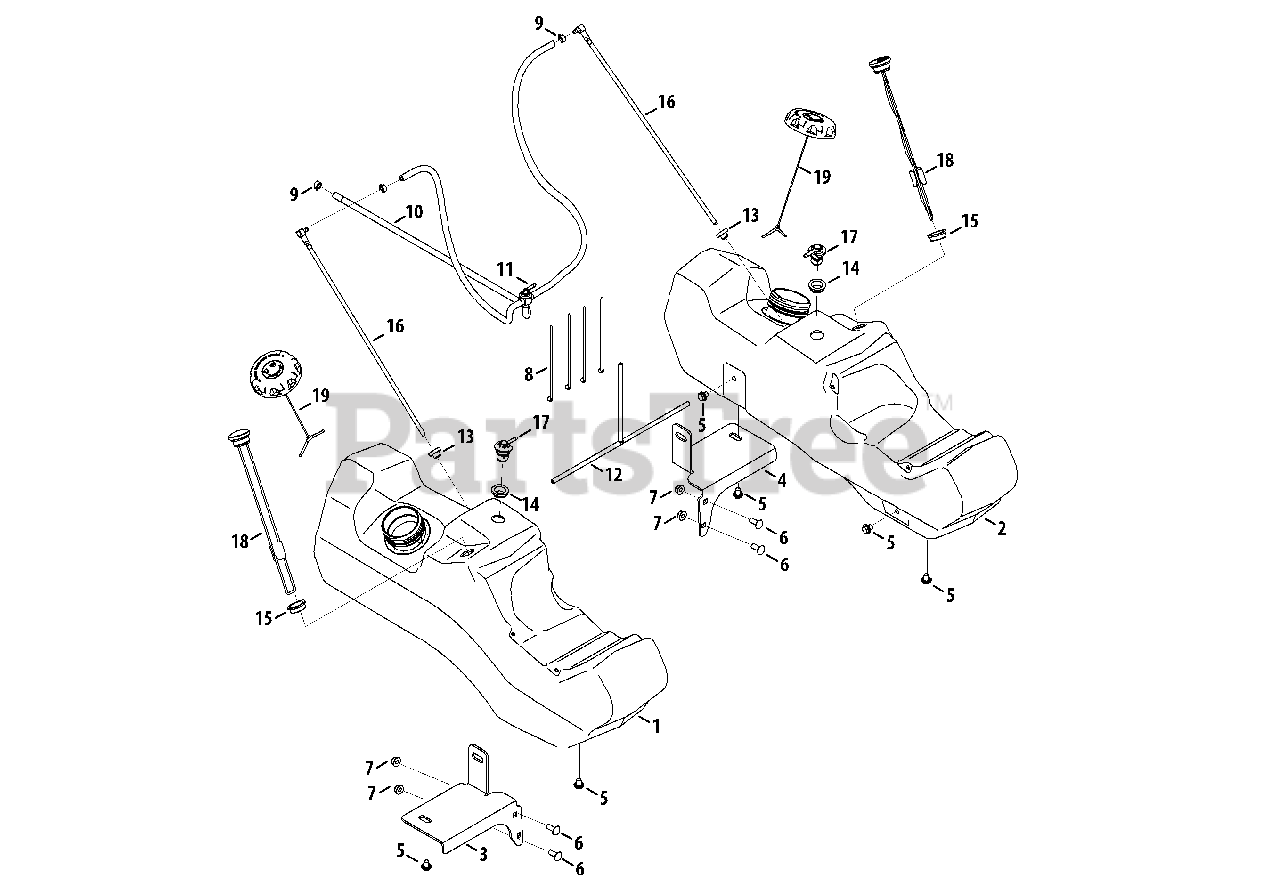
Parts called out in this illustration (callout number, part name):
1	Fuel Tank Assembly, RH
2	Fuel Tank Assembly, LH
3	Rear Fuel Bracket, RH
4	Rear Fuel Bracket, LH
5	Hex Cap Screw, 3/8-16 x .500
6	Carriage Bolt, 3/8-16 x .500
7	Nut, 3/8-16, Flangelock
8	Cable Tie
9	Hose Clamp, .500 Dia.
10	Fuel Hose., 1/4
11	Fuel Switch
12	Fuel Hose Assembly includes:
12	Hose, 3/16" Fuel Line (in inches)
12	Tee Fitting, Fuel
13	Grommet, Fuel Tank
14	Rubber Grommet
15	Grommet, 1.58 OD x 1.21 ID x .5
16	Fuel Pickup Valve
17	Fuel Rollover Valve
18	Fuel Gauge
